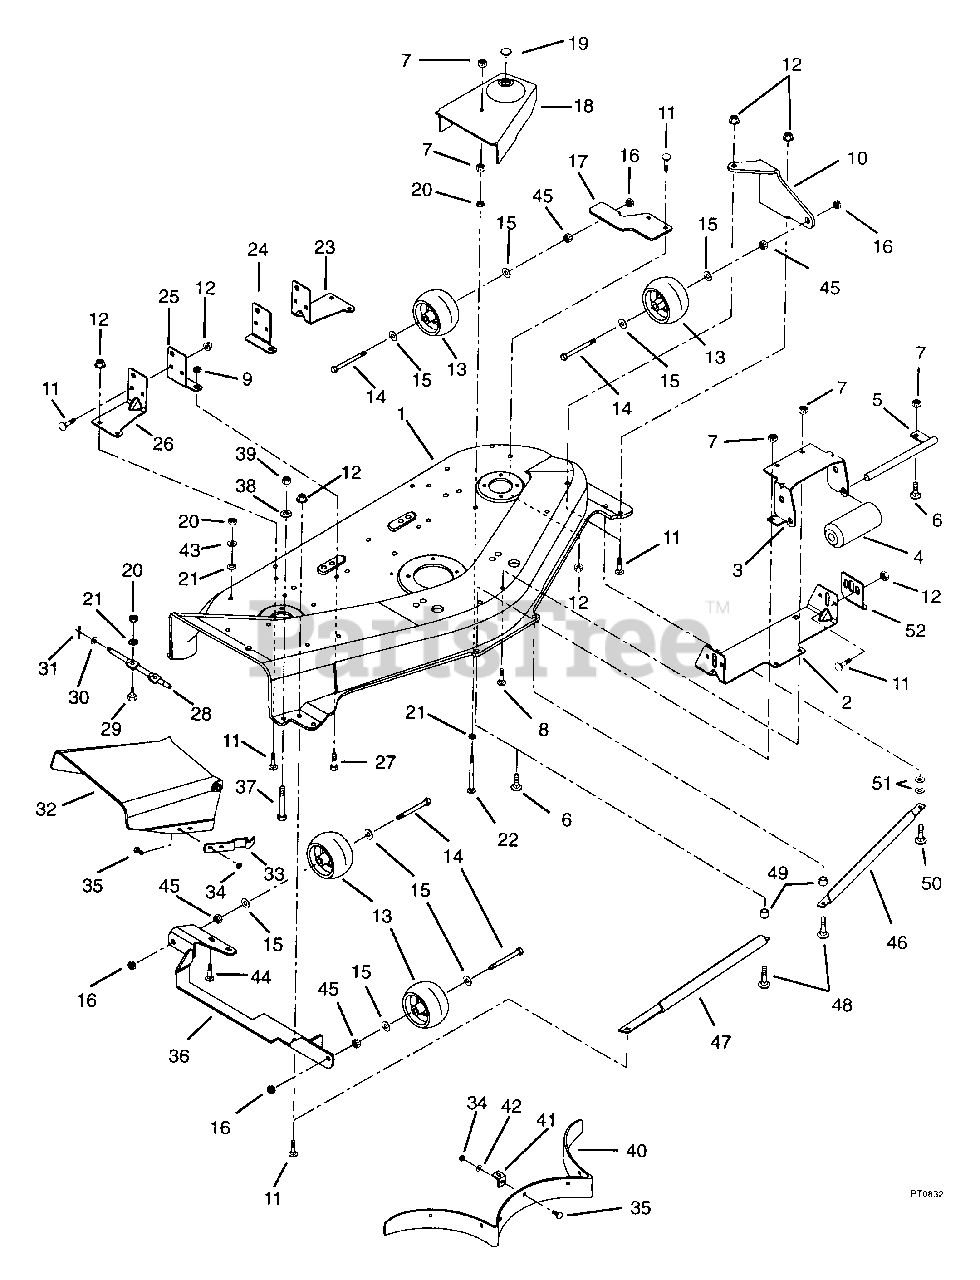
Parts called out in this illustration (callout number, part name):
1	MOWER PAN W/DECALS 48"- ORANGE
2	FRONT HANGER
3	BRACKET, ROLLER
5	ROLLER SHAFT
6	BLT-RDHDSQNK .31-18X.75 GR5 PL
7	NUT-LK .312-18 GR A PL
8	BLT-RDHDSQNK .312-18X.62 PL
9	NUT-LK-NYL .50-13 GR 5 PL
10	BRACKET - LEFT FRONT
11	BLT-RDHDSQNK.31-18X.75GR5SHTPL
12	NUT-FLG. .312-18 PL
13	WHEEL 5 X 3
14	BLT-HEX .50-13X4.00
15	WSHR-FL-NYL .518X1.000X.080
16	NUT-LK .50-13 HEX TYPE N
17	BRACKET - LEFT REAR
18	COVER, R.H. BELT
18	BELT COVER L H 48"
19	BUTTON PLUG 1.0
20	NUT-HEX .312-18
21	WSHR-LK .312X.097 PL HVY
22	BLT-RDHDSQNK .31-18X3.25 SHTPL
23	LH REAR HANGER
24	LH REAR HANGER SUPPORT
25	RH REAR HANGER SUPPORT
26	RH REAR HANGER
27	BLT-HEX .50-13X1 PL GR5
28	HINGE PIN
29	BLT-HEX .31-18X.75 PL GR5
30	WSHR-FL-STL.406X.812X.065PL
31	PIN-COTR .09X.75 PL
32	CHUTE EXTENSION
33	SPRING, FLAT
34	NUT-LK-CTR .250-20 PL
35	BLT-RDHDSQNK .25-20X.50 SHT PL
36	MOUNT - ROLLER
37	BLT-HEX.38-16X2.5FTHD GR2 YWZC
38	WSHR-LK .375X.115 HVY PL
39	NUT-HEX .375-16
40	BAFFLE
41	BAFFLE TAB
42	WSHR-FL-STL.281X.62X.065 PL
43	WSHR-FL-STL.312X.734X.065PL
44	BLT-RDHDSQNK .31-18X1.00 PL
45	NUT-LK-CTR .50-13
46	GUARD - FOOT - LH
47	GUARD - FOOT - RH
48	BLT-RDHDSQNK .31-18X1.50 PL
49	SPACER .375 X .625 X .500
50	BLT-RDHDSQNK .31-18X1.25
51	WSHR-FL-STL .390X.750X.125 PL
52	MOWER ADJUSTMENT TAB
